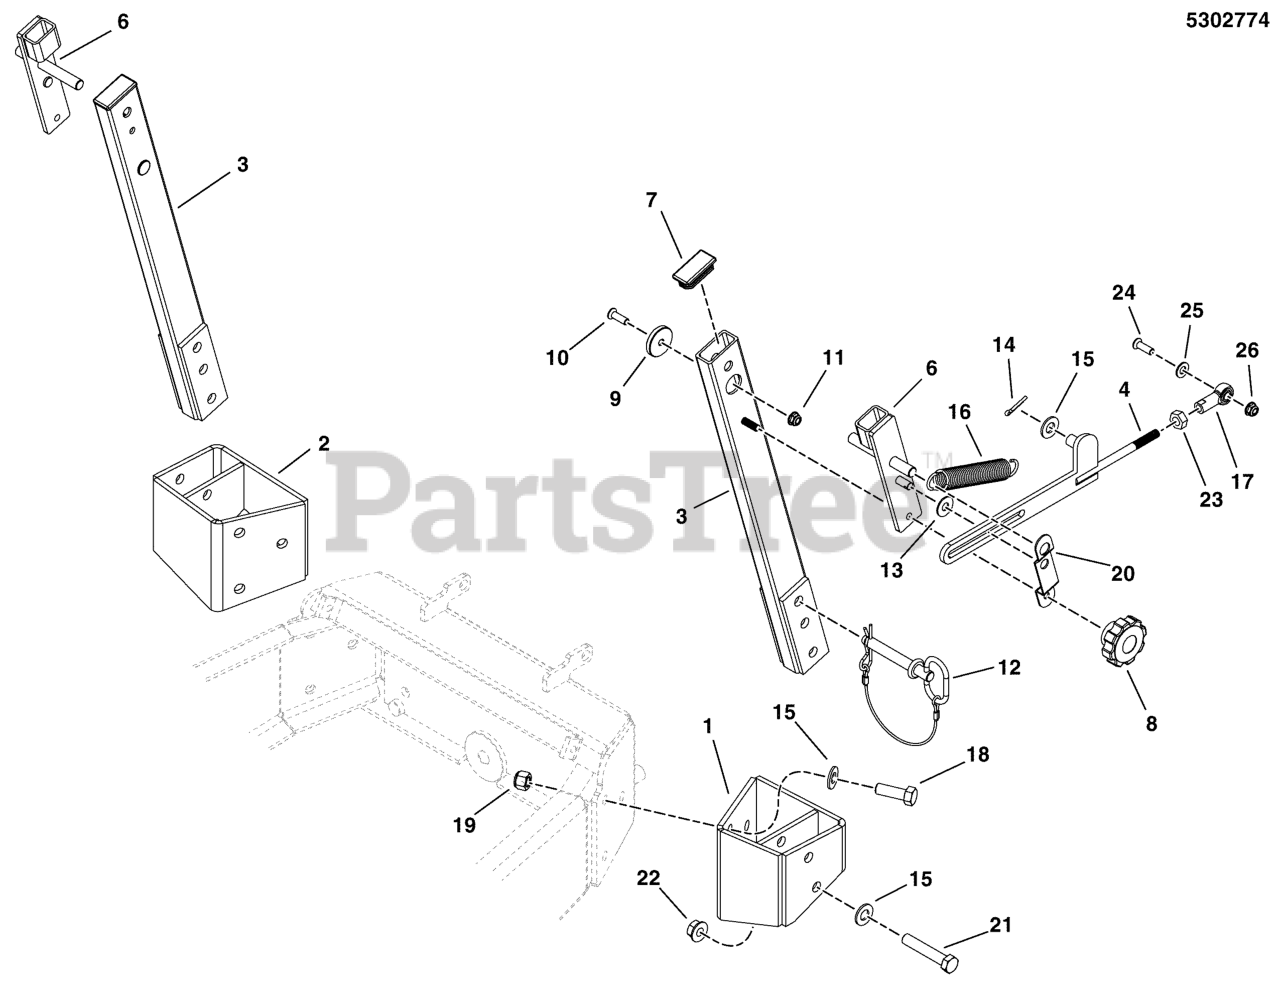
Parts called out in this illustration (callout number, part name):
1	WELD, MOUNT, LH, 800X - BLK
2	WELD, MOUNT, RH, 800X - BLK
3	WELD, TUBE FRAME-BLK
4	WELD, LEFT LATCH PULL, ZTR - BLK
6	WELD, HOPPER LOCK, 800X-BLK
7	PLUG, 1 X 2, 10-14 GA. TUBING
8	KNOB-INT THR .312-18 4-ARM 2.12WD 1.06LG
9	SPACER, .34 X 1.54 X .25 UHMW
10	SCREW, 5/16-18 X 1 PHILLIPS HD, BZ
11	NUT, 5/16-18 HEX NYLOCK FLANGE
12	PIN, HITCH, .50 X 3.25 W/ LAY
13	WASHER, 3/8 X 1 X 1/16, NYLON F/W
14	PIN, 3/32 X .750, COT, ZINC/CLEAR
15	WASHER, 1/2 SAE
16	SPRING, EXTENSION, 1.00
17	BALL JOINT, 3/8-24 FEMALE
18	BOLT, 1/2-20 X 1-1/2, GD5 CZ
19	NUT, Hex, Nylon Lock, 1/2-20
20	PLATE, RETAINER CLIP, 800X - BLK
21	BOLT, 1/2-13 X 2-3/4 GD5 CZ
22	NUT, Hex Flange, Nylock, 1/2-13
23	NUT, 3/8-24 HEX JAM
24	BOLT, 3/8-16 X 1-1/2" GD5 CZ
25	WASHER, 3/8 GD.9 FLAT
26	NUT, 3/8-16 HEX NYLOCK FLANGE
